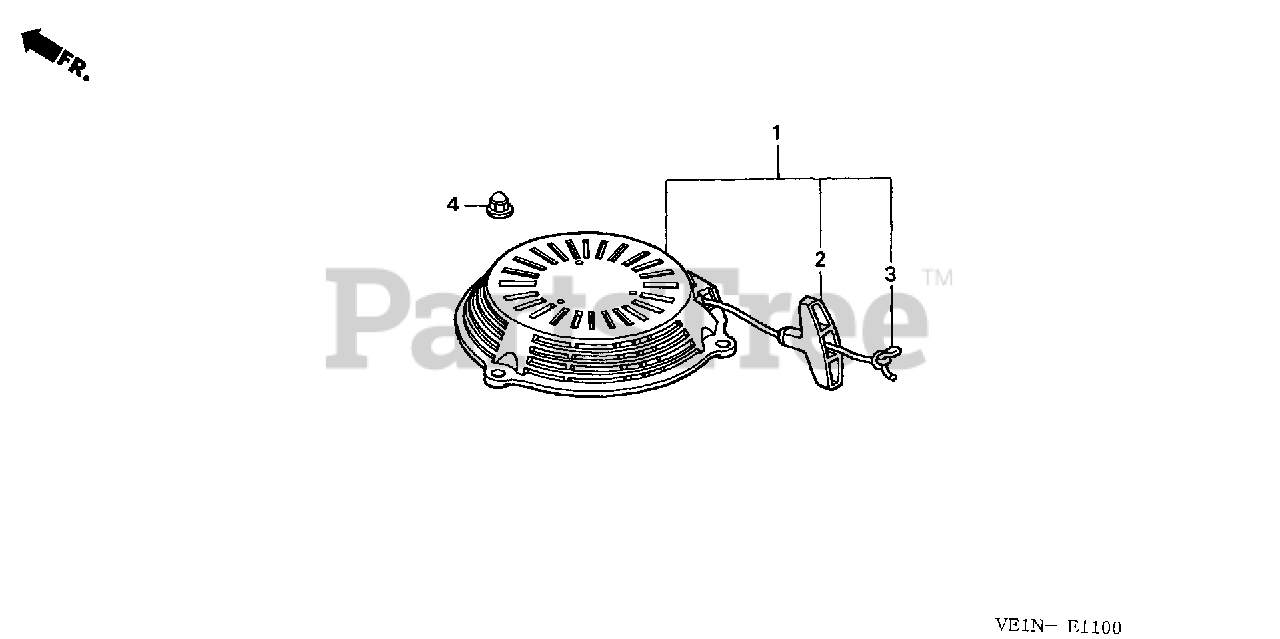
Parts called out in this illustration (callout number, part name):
1	STARTER ASSY., RECOIL *R280* (POWER RED)
2	GRIP, STARTER
3	ROPE, RECOIL STARTER (LONG TYPE)
4	NUT, FLANGE (6MM)
